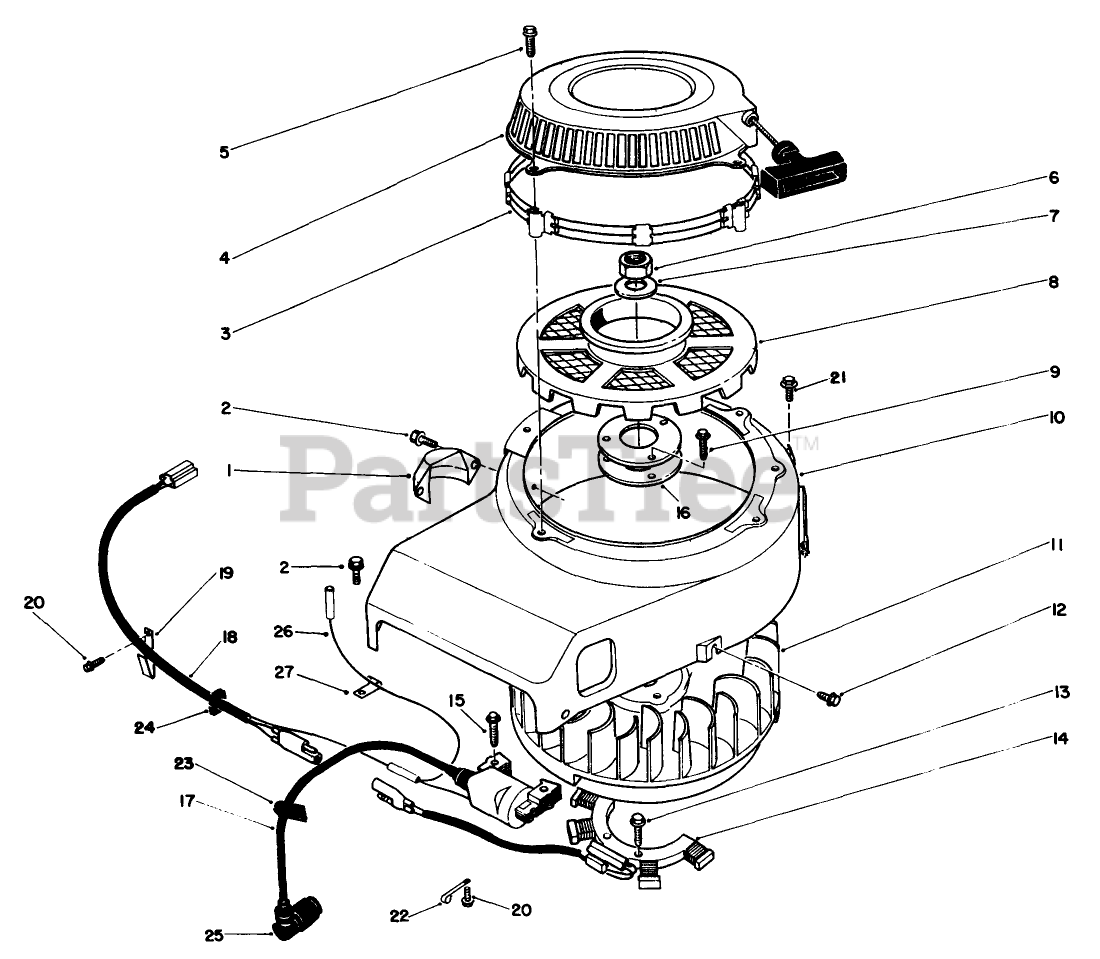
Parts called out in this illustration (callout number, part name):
4	Recoil Starter Assembly
5	BOLT-FLANGED (6X10)
9	Bolt-Flanged (8X12)
10	Housing-Fan
11	Flywheel
12	BOLT-FLANGED (6X10)
18	Harness
20	Bolt-Flanged (6X10)
21	Bolt-Flanged (6X14)
23	Grommet
24	Grommet
25	Cap-Spark
26	Lead Wire
